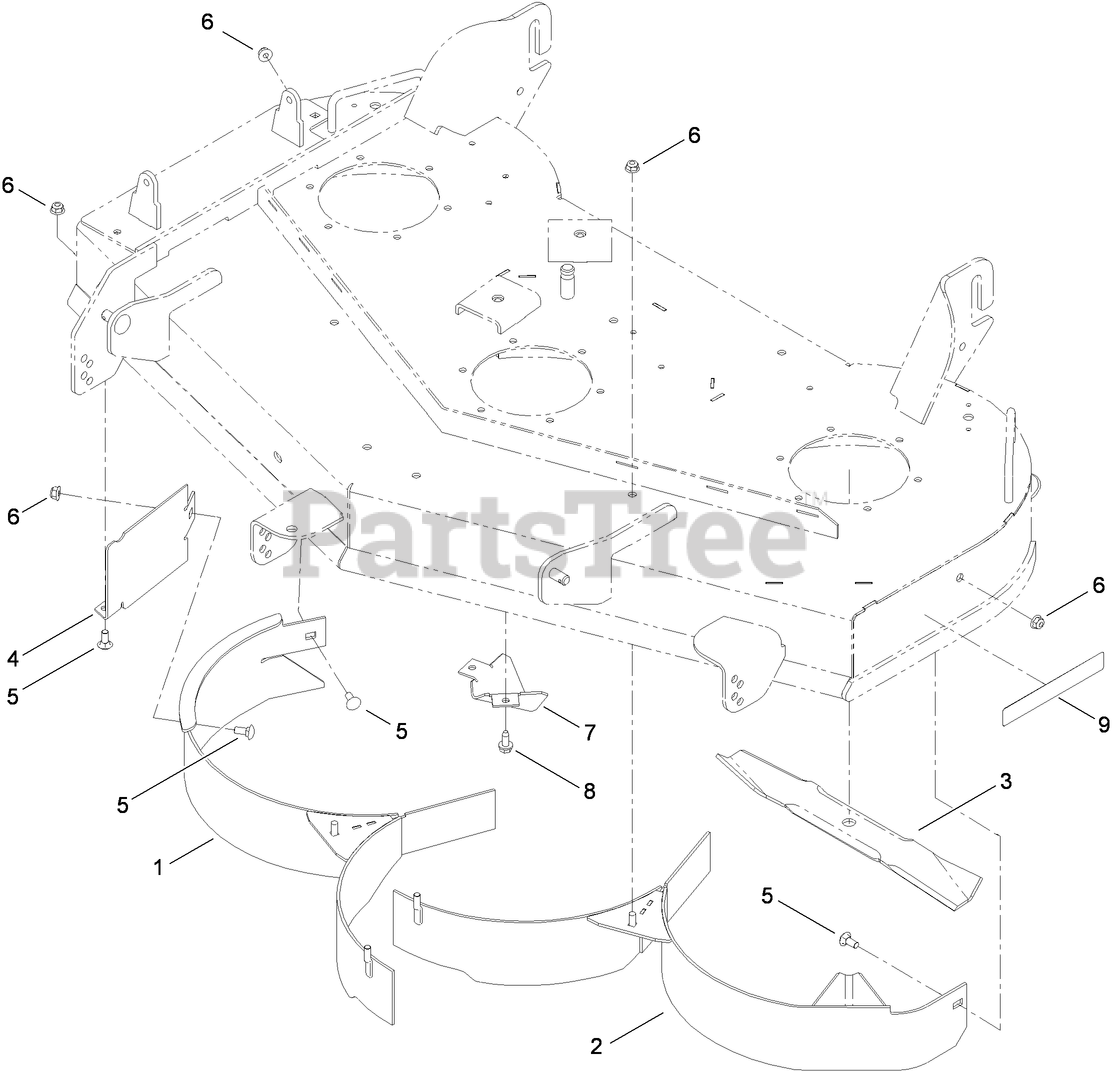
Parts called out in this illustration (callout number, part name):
1	RH BAFFLE ASM
2	LH BAFFLE ASM
3	BLADE-MULCH, 16.50 INCH
4	GUARD-BAFFLE
5	BOLT-CARR
6	NUT-HF, NI
7	KICKER-FLANGED
8	SCREW-HWHTF
9	DECAL-RECYCLER
